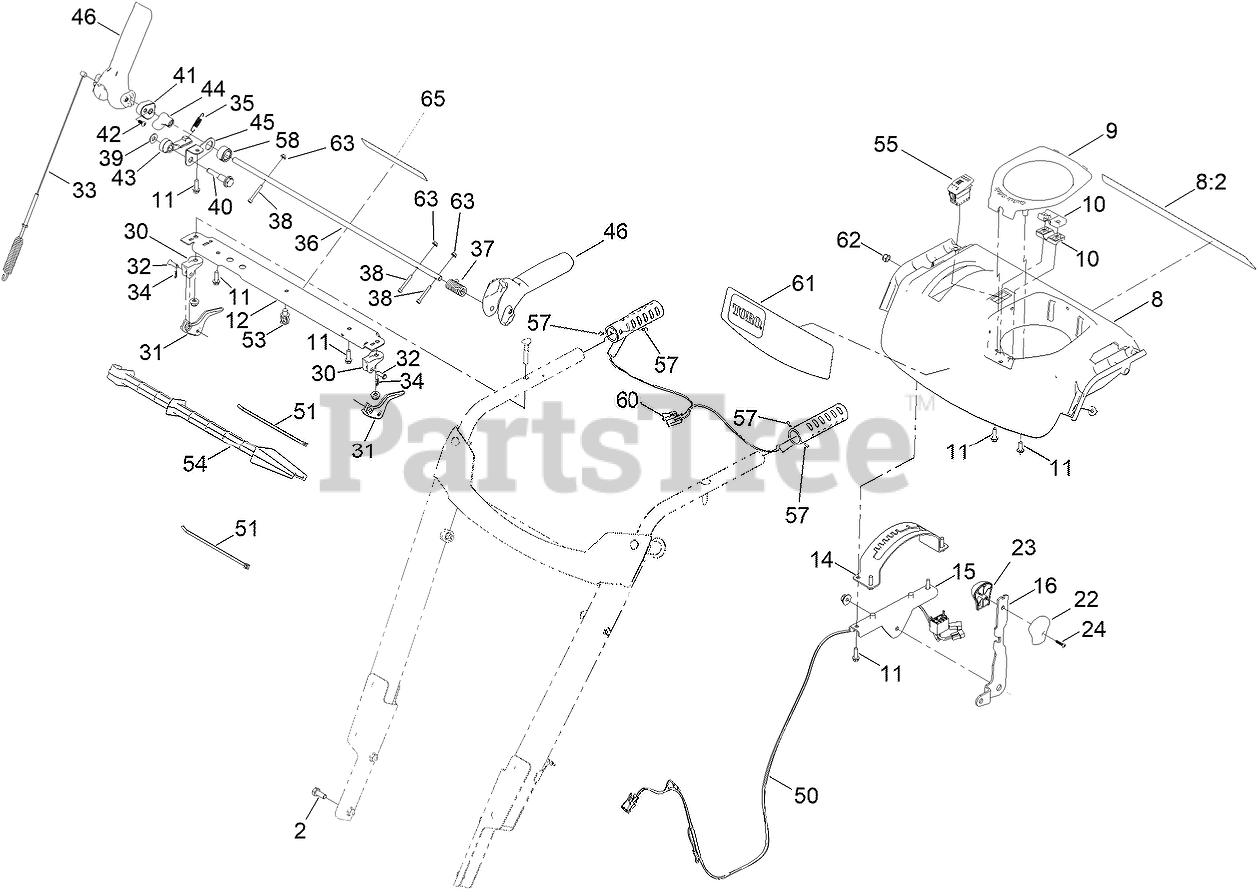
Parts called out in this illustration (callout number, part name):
2	SCREW-HH
8	PANEL-CONTROL, ASSEMBLY
8:2	DECAL-SAFETY
9	COVER-QUICKSTICK
10	SUPPORT-ROD
11	SCREW-PLASTITE, HWH
12	BRACE-CONSOLE
14	GATE-SHIFT
15	BRACKET-SHIFT
16	SELECTOR-SPEED
22	KNOB-SHIFT, LH
23	KNOB-SHIFT, RH
24	SCREW-PPH
30	MOUNT-LEVER, CLUTCH
31	LEVER-CLUTCH
32	PIN-CLEVIS
33	CABLE-AUGER
34	PIN-HAIR
35	SPRING-LOCKOUT, HANDLE
36	ROD-LOCKOUT
37	SPRING-TORSION, HANDLE RETURN
38	SCREW-HSH
39	WASHER-FLAT
40	SCREW-SHOULDER
41	LOCK-HANDLE
42	SCREW-PPH
43	LATCH-LOCKOUT
44	CAM-LOCKOUT
45	LINK-LOCKOUT
46	LEVER-CONTROL
50	HARNESS-WIRE, LED AND HAND WARMERS
51	TIE-CABLE
53	CLIP-TIE
54	STICK-CLEANOUT
55	SWITCH-ROCKER, ON-NONE-OFF (HEATER)
57	RIVET-POP
58	COLLAR-CAM
60	GRIP-HEATED
61	DECAL-CONSOLE
62	NUT-HEX
63	NUT-LOCK ROHS
65	DECAL-HYDRO
